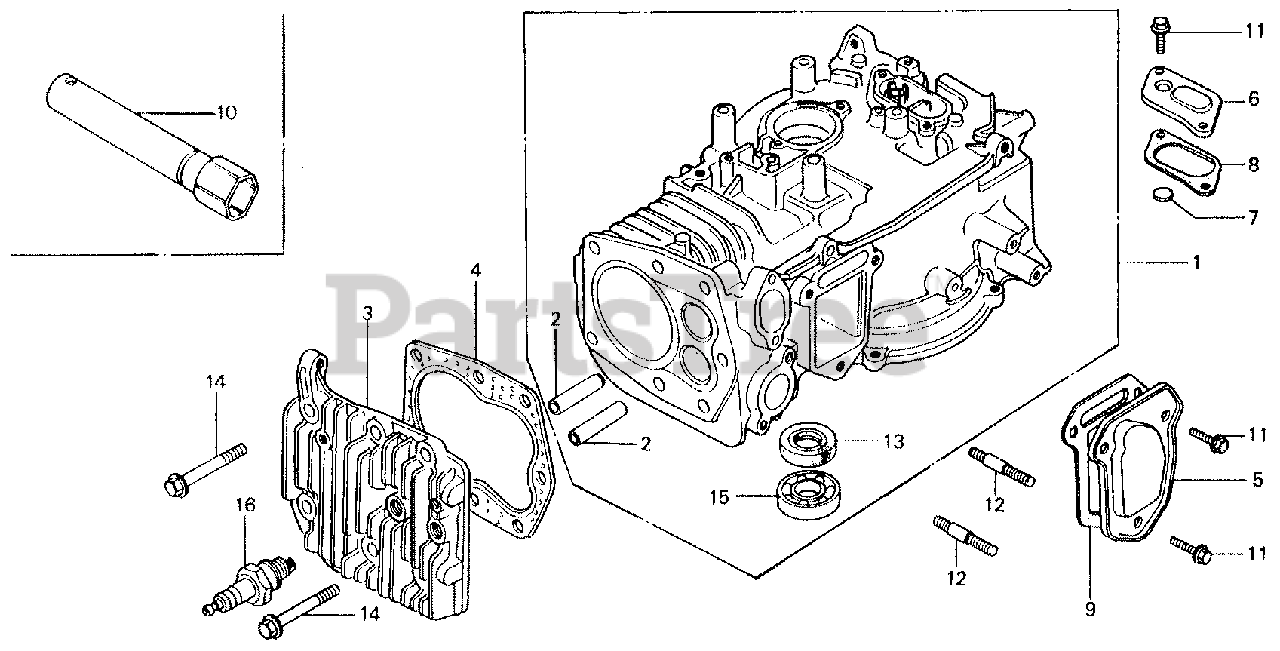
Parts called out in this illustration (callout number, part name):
1	CYLINDER ASSY.
2	GUIDE, VALVE (OS)
3	CYLINDER HEAD
4	GASKET, CYLINDER HEAD
5	COVER, TAPPET
6	CAP, BREATHER CHAMBER
7	VALVE, BREATHER
8	GASKET, BREATHER CAP
9	GASKET, TAPPET COVER
10	WRENCH, SPARK PLUG
11	BOLT, FLANGE (6X12) (CT200)
13	OIL SEAL (25X41X6)
14	BOLT, FLANGE (8X45)
15	BEARING, RADIAL BALL (6205)
16	SPARK PLUG (BPMR6A-10) (NGK)
16	SPARK PLUG (W20MPR-U10) (DENSO)
